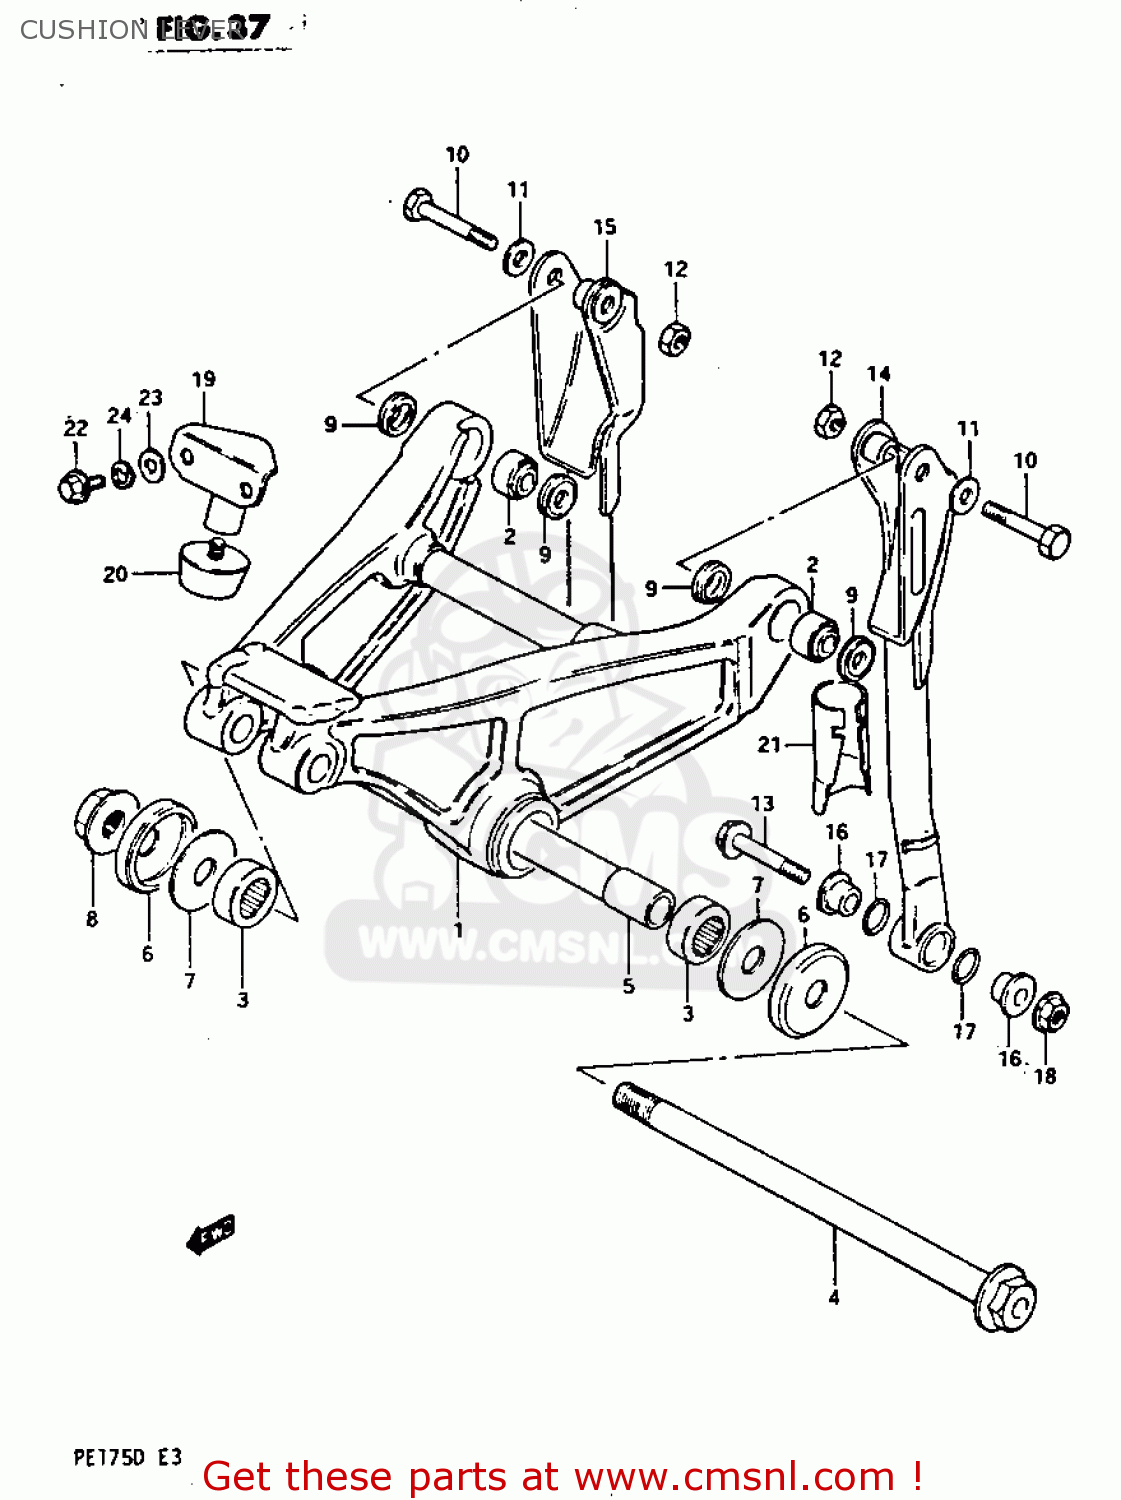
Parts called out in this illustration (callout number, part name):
1	LEVER SET,REAR CUSHION
2	BEARING(8X18X11)
3	BEARING(17X26X20)
4	SHAFT,REAR CUSHION LEVER
5	SPACER,REAR CUSHION LEVER
6	DUST SEAL,REAR CUSHION,LEFT
7	WASHER
8	NUT 12MM
9	DUST SEAL,RR CUSHION LOD UPR.
10	BOLT 8X38
11	WASHER
12	NUT
13	BOLT(8X45)
14	ROD,REAR CUSHION LEVER,LEFT
15	ROD,REAR CUSHION LEVER,RIGHT
16	SPACER,RR CUSHION ROD LWR
17	DUST SEAL,RR CUSHION LOD LWR
18	NUT
19	STOPPER,TENSION
20	RUBBER,TENSION STOPPER
21	PROTECTOR,REAR CUSHION R
22	BOLT
23	WASHER
24	WASHER,LOCK
